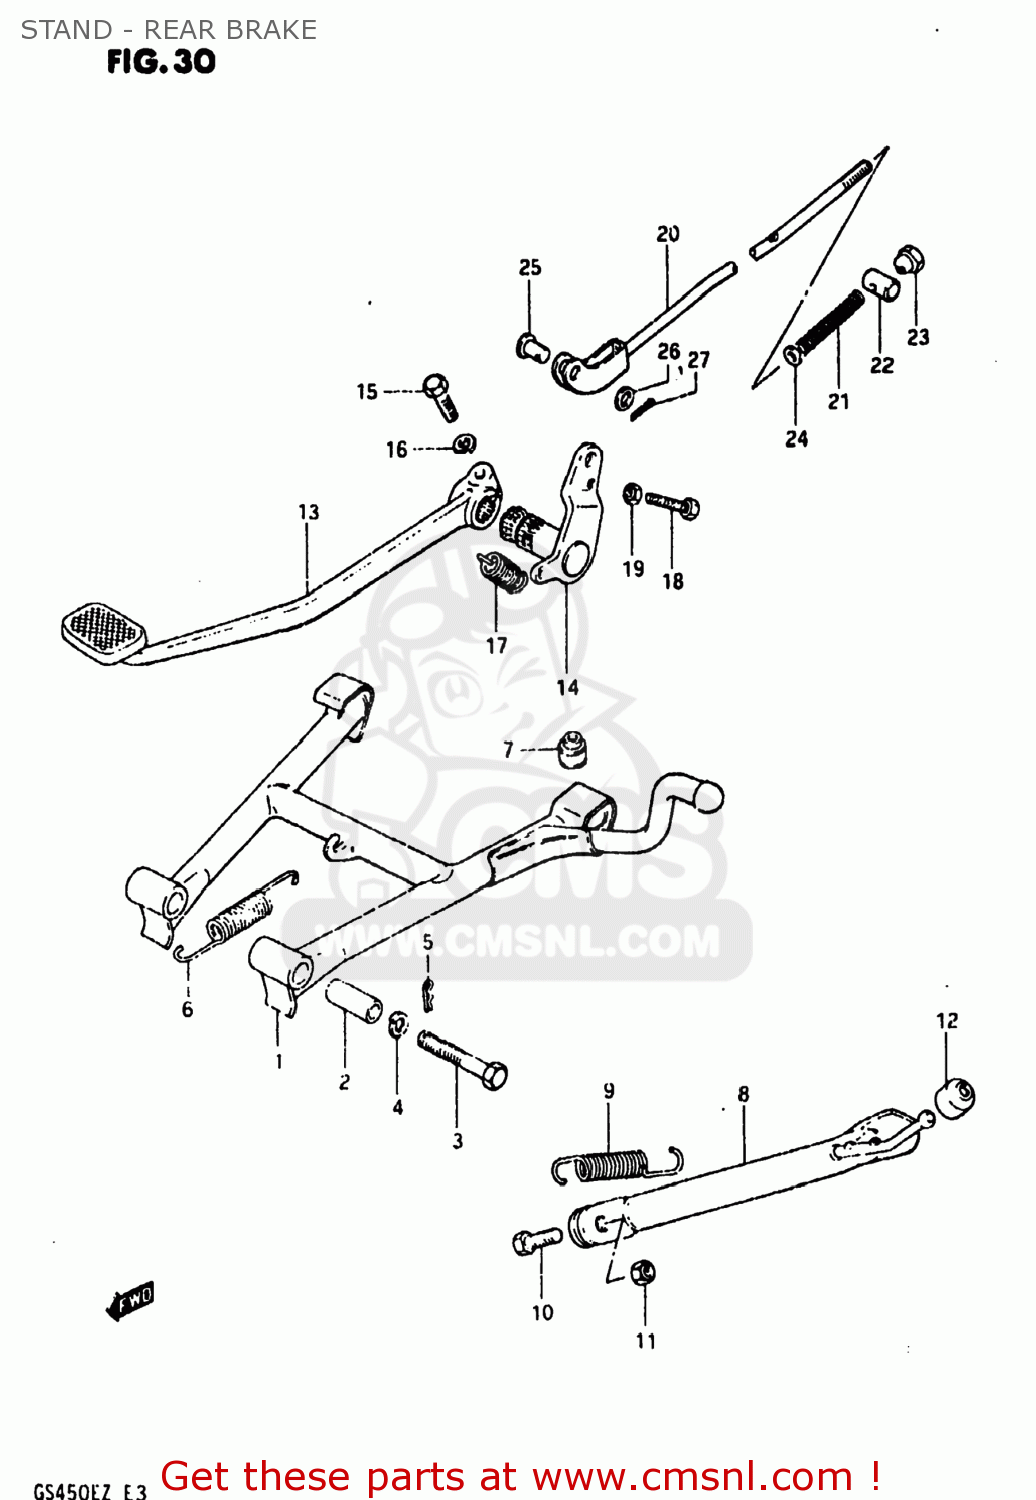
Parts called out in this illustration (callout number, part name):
1	STAND,CENTER
2	SPACER(10X16X38.8)
3	BOLT
4	LOCK WASHER
5	CLIP
6	SPRING
7	CUSHION
8	STAND,SIDE
9	SPRING
10	BOLT(10X30)
11	NUT
12	CUSHION
13	PEDAL,BRAKE
14	ARM,BRAKE PEDAL ROD
15	BOLT
16	LOCK WASHER
17	SPRING
18	BOLT
19	NUT
20	ROD ASSEMBLY,REAR BRAKE
21	SPRING
22	PIN
23	NUT
24	WASHER
25	PIN(L:13.5)
26	WASHER
27	PIN 20X20
